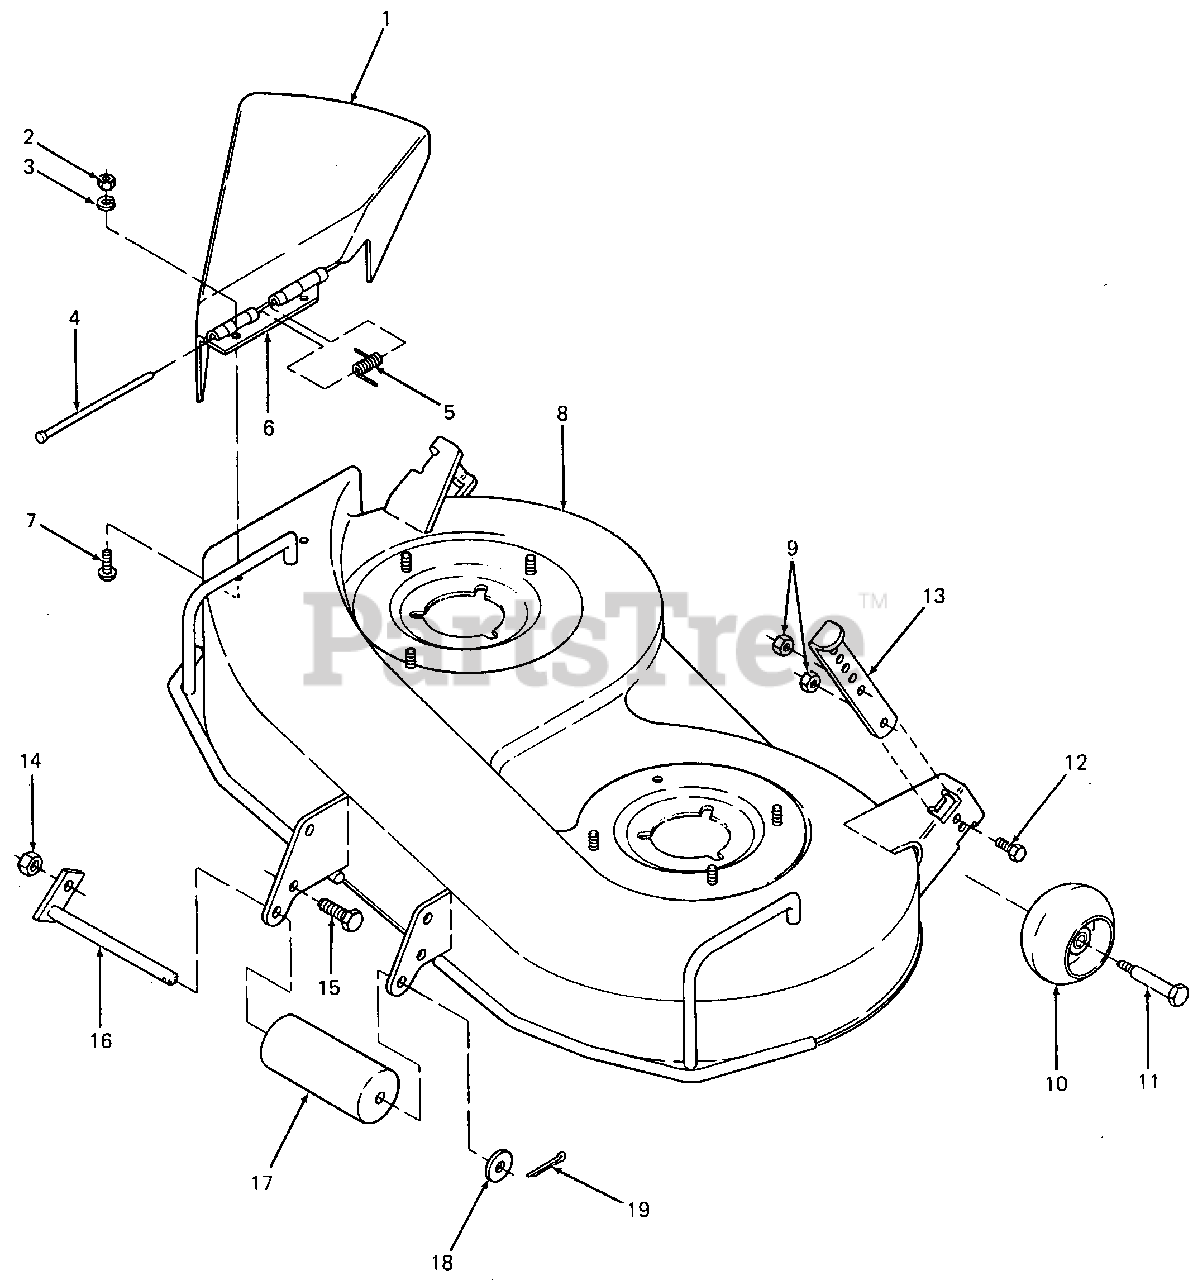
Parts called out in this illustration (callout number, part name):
1	Chute, Discharge w/Graphic
2	Nut, Hex Jam, 1/4-20
3	Washer, Lock, 1/4
4	Pin, Hinge, .25 Dia X 6.75 Lg
5	Spring, Torsion, .29 ID x 1.14 Lg
6	Hinge, Discharge Chute
7	Screw, Truss Mach, 1/4-20 X .75 Lg
8	Deck Assy w/Graphics
9	Nut, Hex Center Lock, 3/8-16
10	Wheel, Ball, 5" Dia
11	Screw, Shoulder
12	Screw, Hex Cap, 3/8-16 X 1.0 Lg GR5
13	Bar, Height Adjustment
14	Nut, Hex Center Lock, 1/2-13
15	Screw, Hex Cap, 1/2-13 X 1.0 Lg GR5
16	Pin, Roller
17	Roller, Front
18	Washer, Flat, .531 X 1.25 X .100 Thk
19	Pin, Cotter, 1/8 Dia X 1.25 Lg
